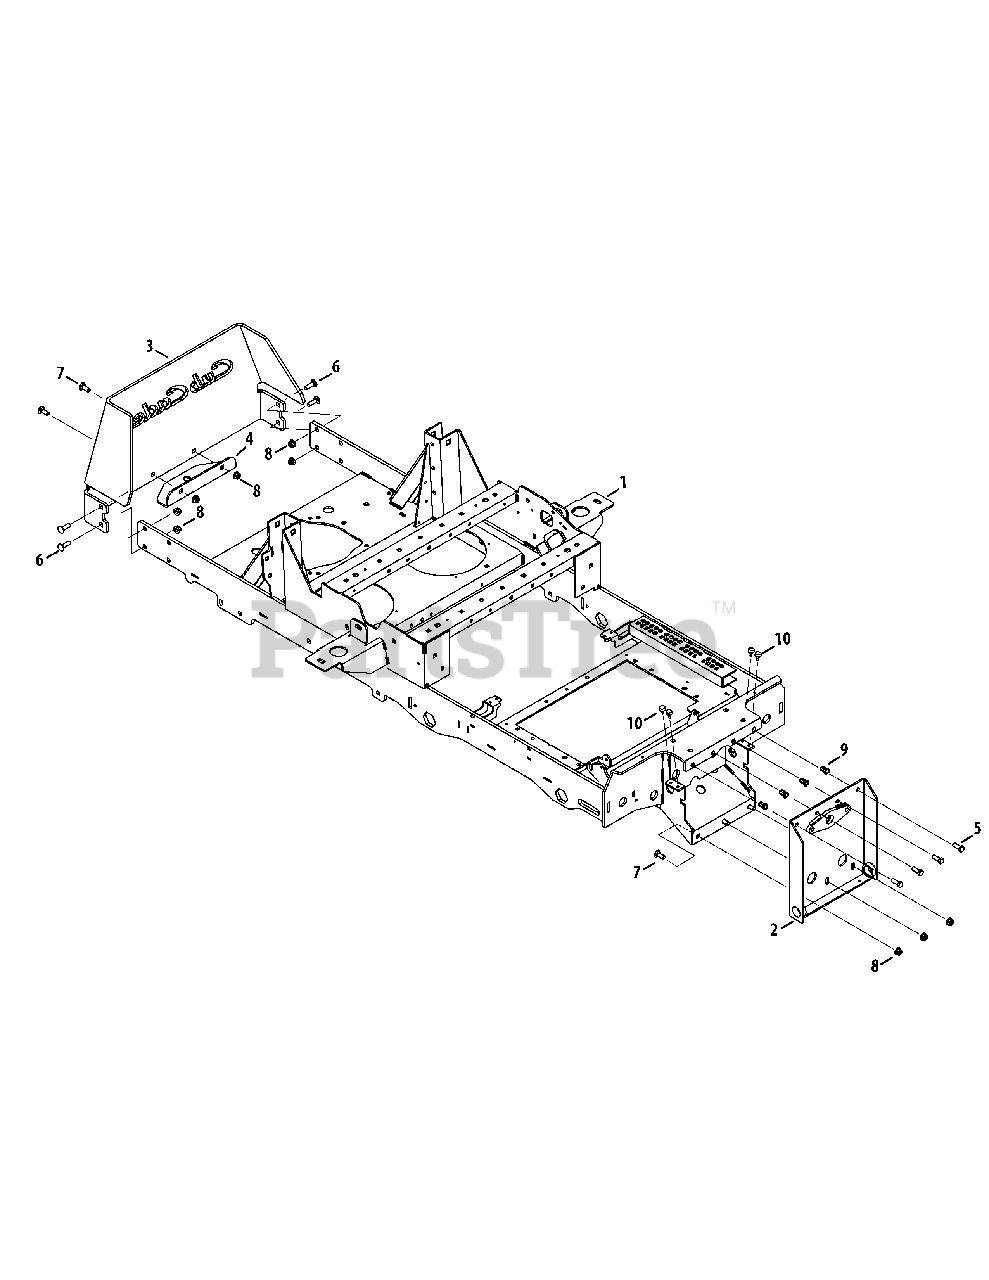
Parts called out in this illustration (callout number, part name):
1	Frame Assembly
2	Front Axle Bracket Assembly
4	Hitch Bracket
5	Hex Cap Screw, 3/8-16 x 1.00
6	Carriage Bolt, 3/8-16 x 1.25
7	Carriage Bolt, 3/8-16 x 1.00
8	Nylock Nut, 3/8-16
9	Rivet Nut, 3/8-16
10	Bumper, .62 Dia. x .3
